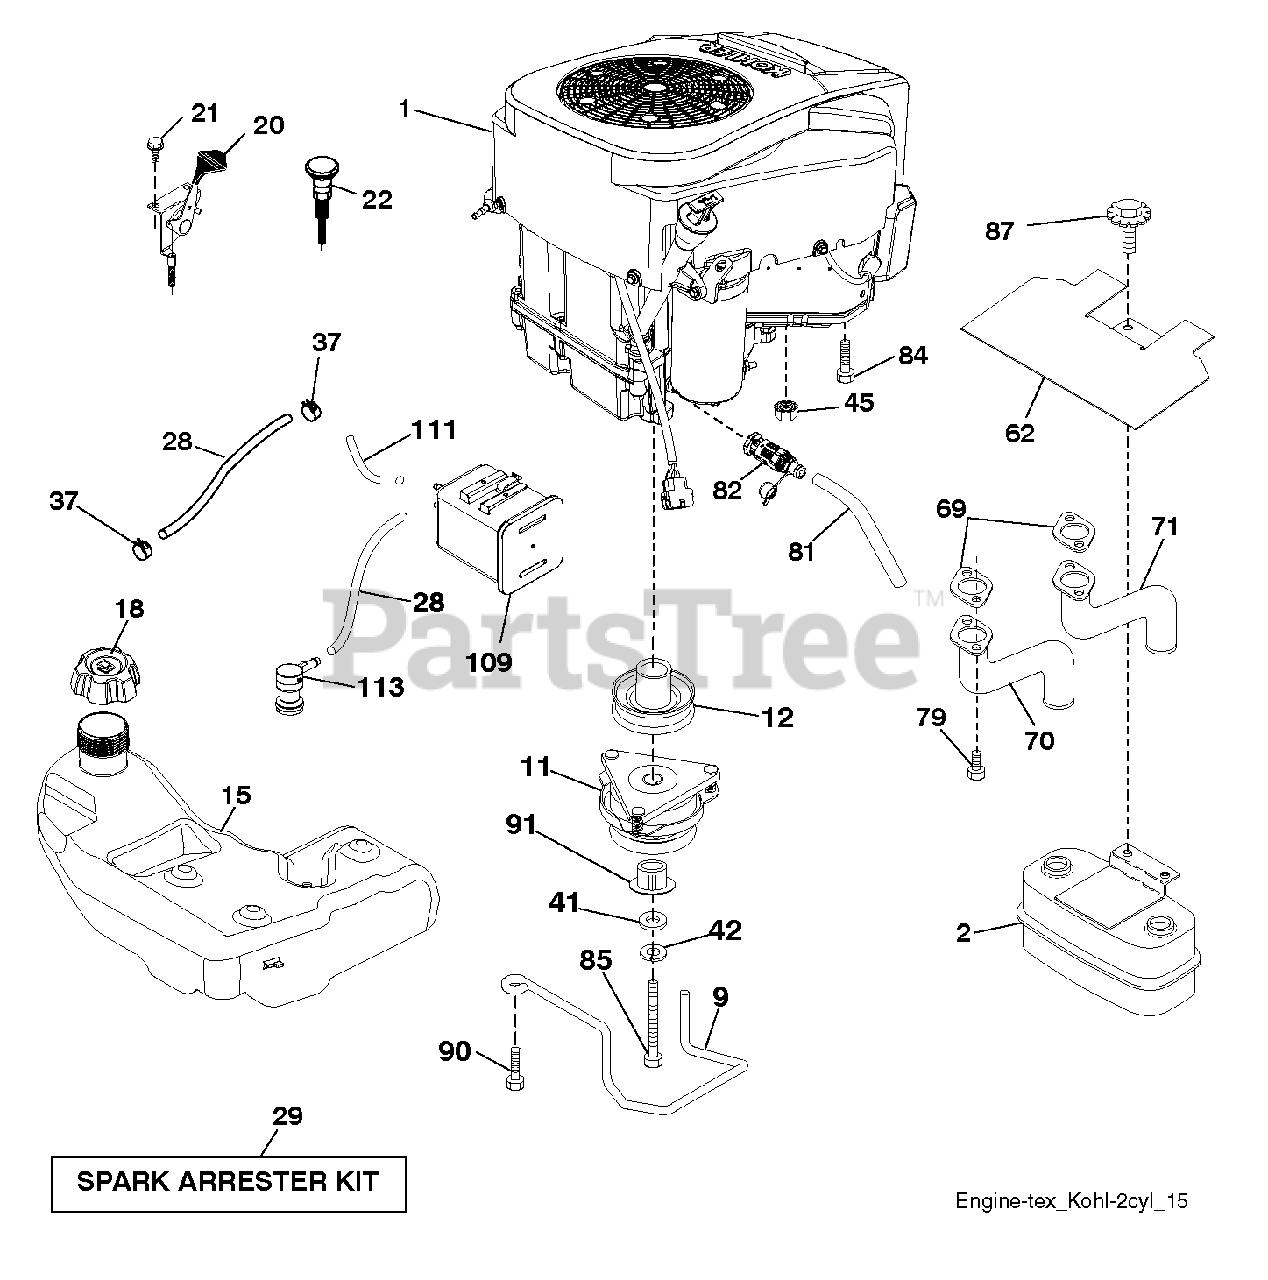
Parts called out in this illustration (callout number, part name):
2	MUFFLER.ASM.TWN.EXTNDED.DFLCTR
9	KEEPER BELT ENGINE
11	CLUTCH.ELECTRIC.LT.48"*
12	PULLEY.ENGINE.TUFFTORQ
15	TANK.ASSY.3.GAL.EPA
18	CAP.ASM.FL.RITCH.3"E10.SYM.498
20	THROTTLE CONTROL
21	SCREW.#10 X 0.750.BOS
22	CONTROL.CHOKE.ERGO.PUSH-IN.BLA
28	LINE.FUEL.64"REAR.EMIS
29	KIT.SPARK ARRESTOR 794945 B&S
37	HOSE CLAMP
42	LOCKWASHER
45	NUT
62	SHIELD.HEAT.MUFFLER
69	GASKET.EXHAUST.KOHL.CV18-CV26
70	RP.PIPE-EXHAUST LH
71	RP.PIPE-EXHAUST RH
79	SCREW.SOCKET HD.5/16-1
81	TUBE, DRAIN OIL ASM.
82	VALUE.OIL.DRAIN
84	SCREW 3/8-16X1
85	BOLT HEX 7/16-20X4-1/4"
87	BOLT, 5/16-18 X 1 3/4
90	SCREW 3/8-16X1
91	PARTNER DECAL,
109	CANNISTER, CARBON
111	PURGE.LINE.36"REAR.CALIFORNIA
113	VALVE.SLANT.CARTRDG.90 DEG.TEX
